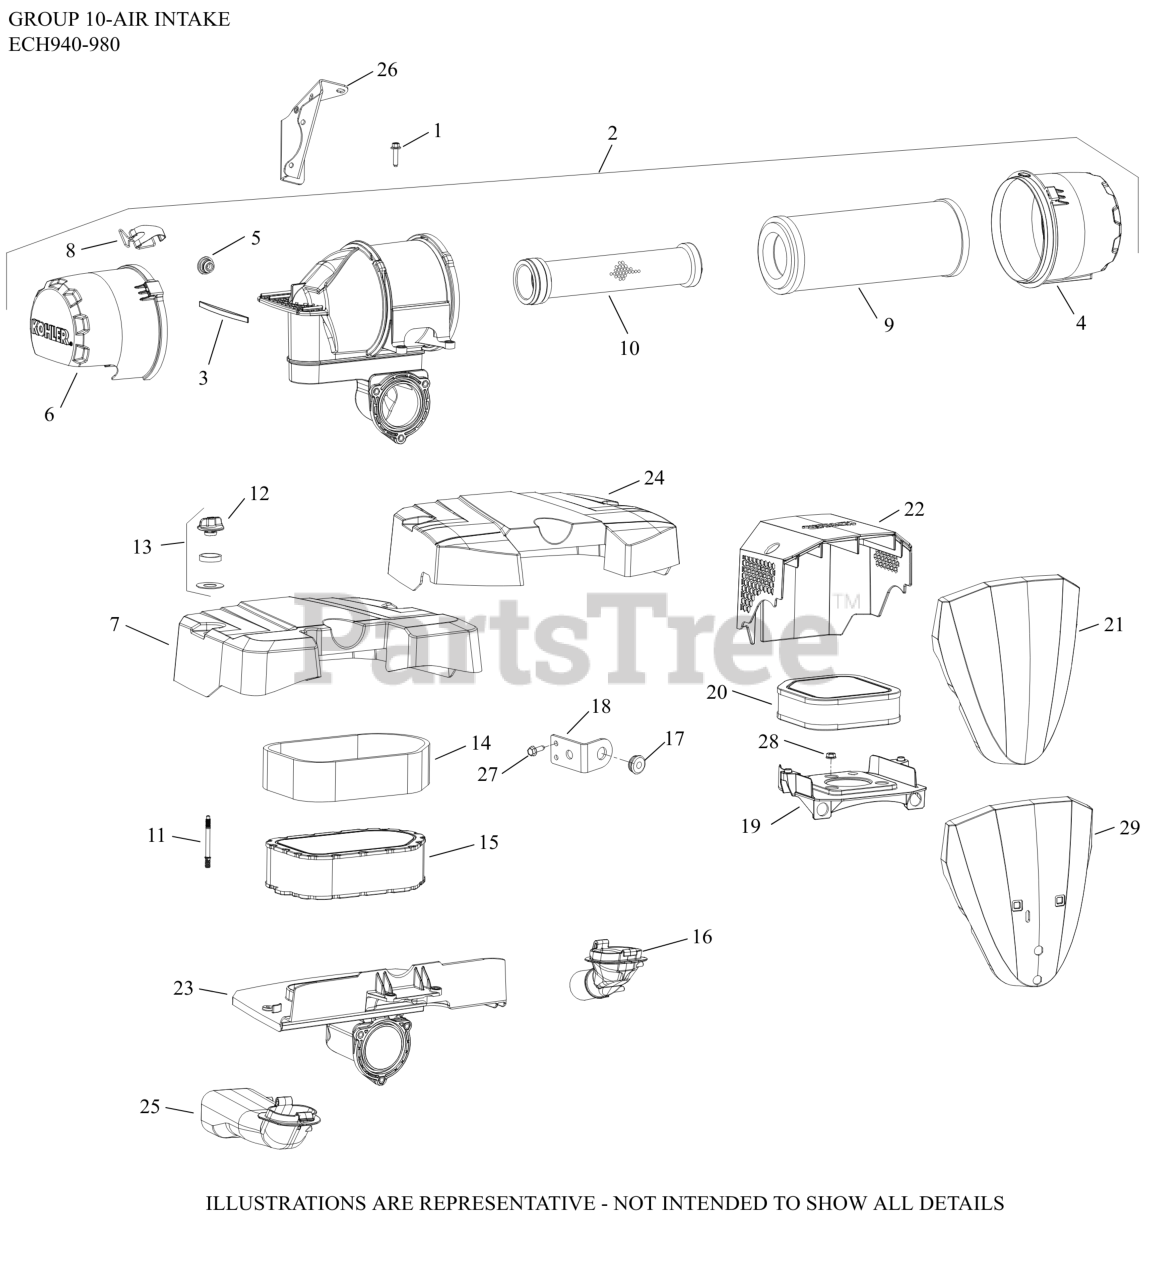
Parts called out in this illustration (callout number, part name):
1	SCREW, FLG M6X1.0X25
2	FILTER ASSEMBLY, AIR
3	DAMPER, FOAM INSERT
4	COVER, AIR FILTER
5	PLUG, HOLE
6	COVER, RAIN CAP
8	CLIP ASSEMBLY
9	ELEMENT, AIR FILTER - PRIMARY
10	ELEMENT, AIR FILTER - SAFETY
23	BASE, AIR CLEANER
